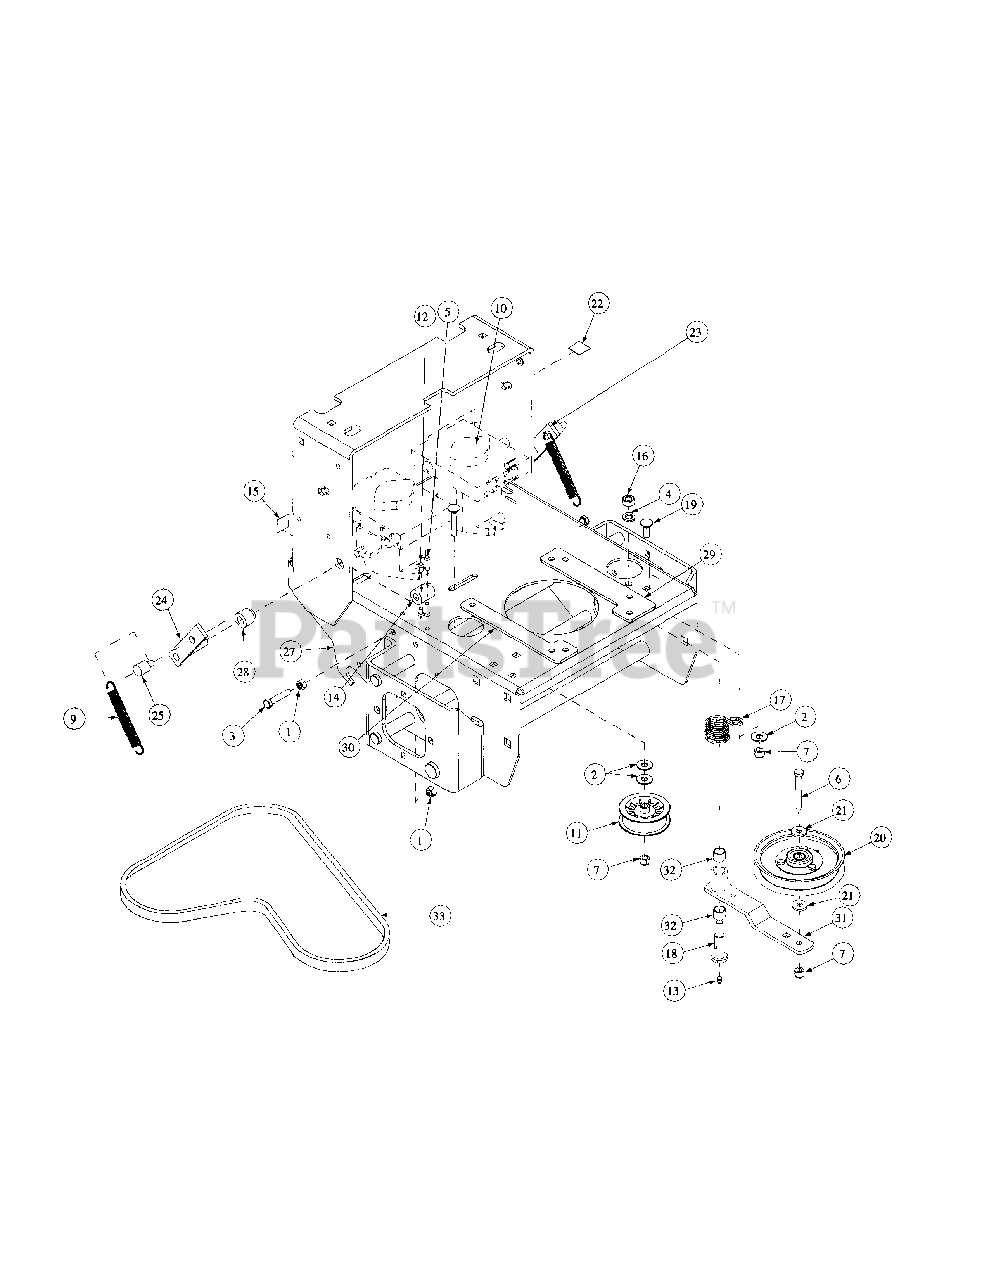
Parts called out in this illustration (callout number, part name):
1	Nut, Hex, 3/8-16
2	Flat Washer, USS 3/8
3	Cap Screw, 3/8-16 x 1-3/4"
4	Wash, Lock, 7/16, Zinc
5	Screw, CP, Square Head Set, 1/4-20
6	HHCS, 3/8-16, 1
7	Nylon Insert, Lock Nut 3/8-16
9	Wire Spring
10	Hydro Pump
11	Flat Idler Pulley with Adapter
12	Cap Screw, Square Head Set, 1/4-20
13	Grease Fitting, 1/4-28 x 3/16
14	Coupling, Trunnion
15	Decal, Made In America
16	Nut, Hex, 7/16-14
17	Spring Idler Torsion
18	Shoulder Bolt
19	Carriage Bolt, 3/8-16 x 2
20	Pulley Assembly, Idler, 5.00"
21	Flat Washer, .406 ID: 1.0 OD: .105
22	Label, Mower, Warn, Open Belt Drive
23	Hydro Pump Lever Assembly, LH
24	Hydro Pump Lever Assembly, RH
25	Pivot, Belt Tightener
27	Engine Base Assembly, Hydro WT
28	Bushing Lever Pump
29	Spacer Engine, RH
30	Spacer Engine, LH
31	Idler Arm with bearings
32	Bearing sleeves
